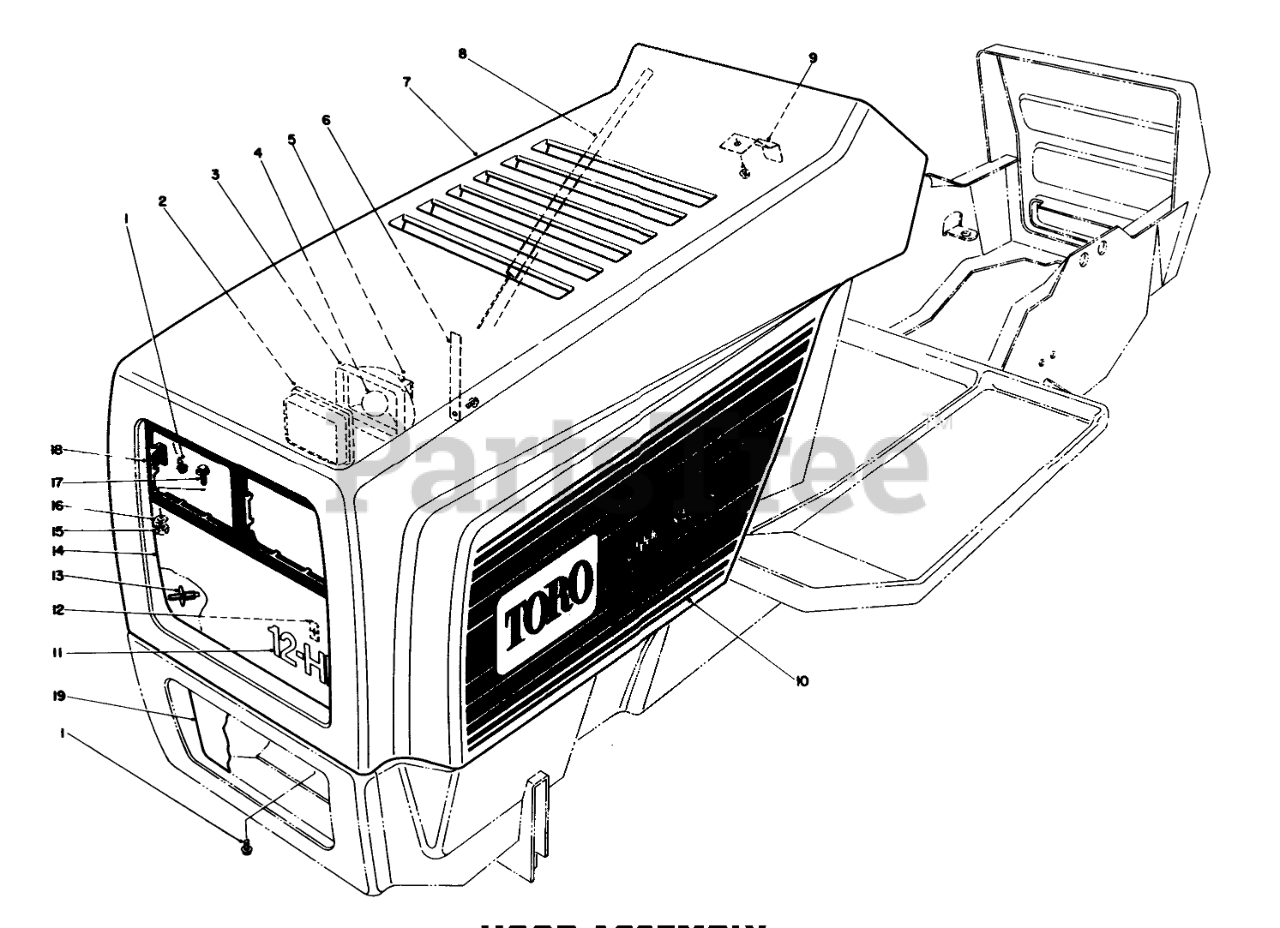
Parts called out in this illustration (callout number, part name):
1	SCREW-HWHTF
2	Lens
3	Reflector
4	Bulb
5	Socket Assembly
6	HEADLIGHT STRAP
7	Hood (Incl. Ref. #13)
8	RUBBER EXT SEAL
9	SPRING LATCH
10	LH HOOD DECAL
11	GRILLE NAMEPLATE
13	HINGE BRKT STUD
14	HEADLIGHT GRILLE
15	NUT-LOCK, SIDE
16	WASHER-FLAT
17	SCREW-SHWH
18	HEADLIGHT PANEL
19	LOWER GRILLE
